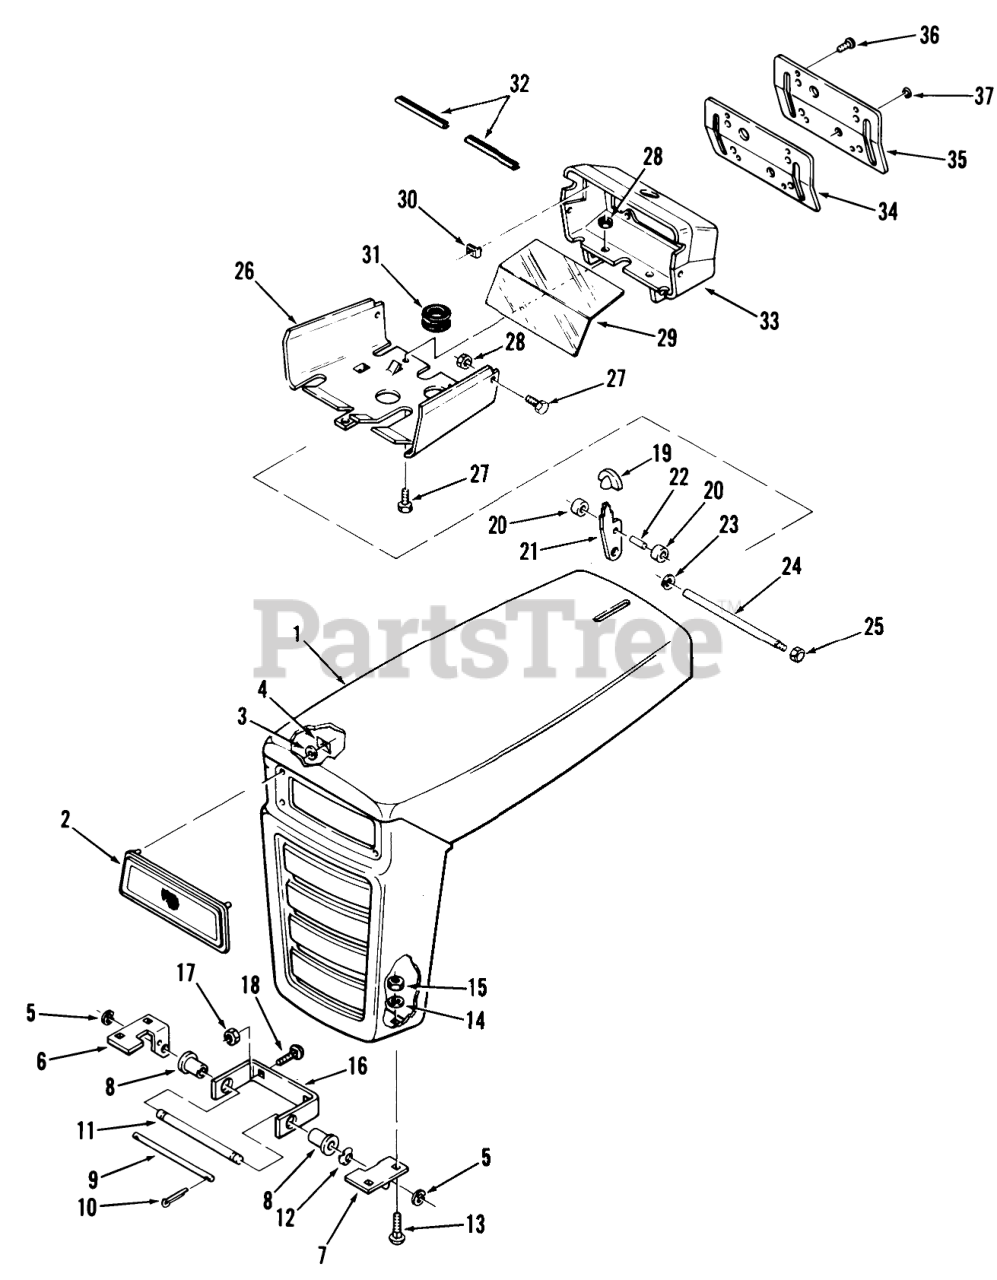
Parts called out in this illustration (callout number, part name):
1	Hood
2	ESCUTCHEON PLATE
3	WASHER
4	SPEED NUT
5	RING-RETAINING
6	Bracket-Grill Pivot RH
7	Bracket-Grill Pivot LH
8	BUSHING-NYLINER
9	ROD PIVOT STOP
10	Cotter Pin
11	Rod-Pivot
12	WASHER-SPRING
13	Bolt
14	WASHER 5/16 SAE
15	Nut
16	Bracket-Hood Pivot
17	Nut
18	Bolt-Carriage
19	KNOB
20	Roller
21	LEVER HOOD LATCH
22	SPIROL PIN
23	SPEED NUT
24	Rod Latch
26	Support-Tank
27	Screw
28	Nut
29	CONTROL PROTECTOR
30	SPEED NUT
31	Grommet
32	EDGE TRIM 4IN OF 102896
33	Housing
34	BACK UP PLATE
35	PLATE-DASH INSTRUMNT
36	SCREW BLACK
37	PLUG BUTTON
